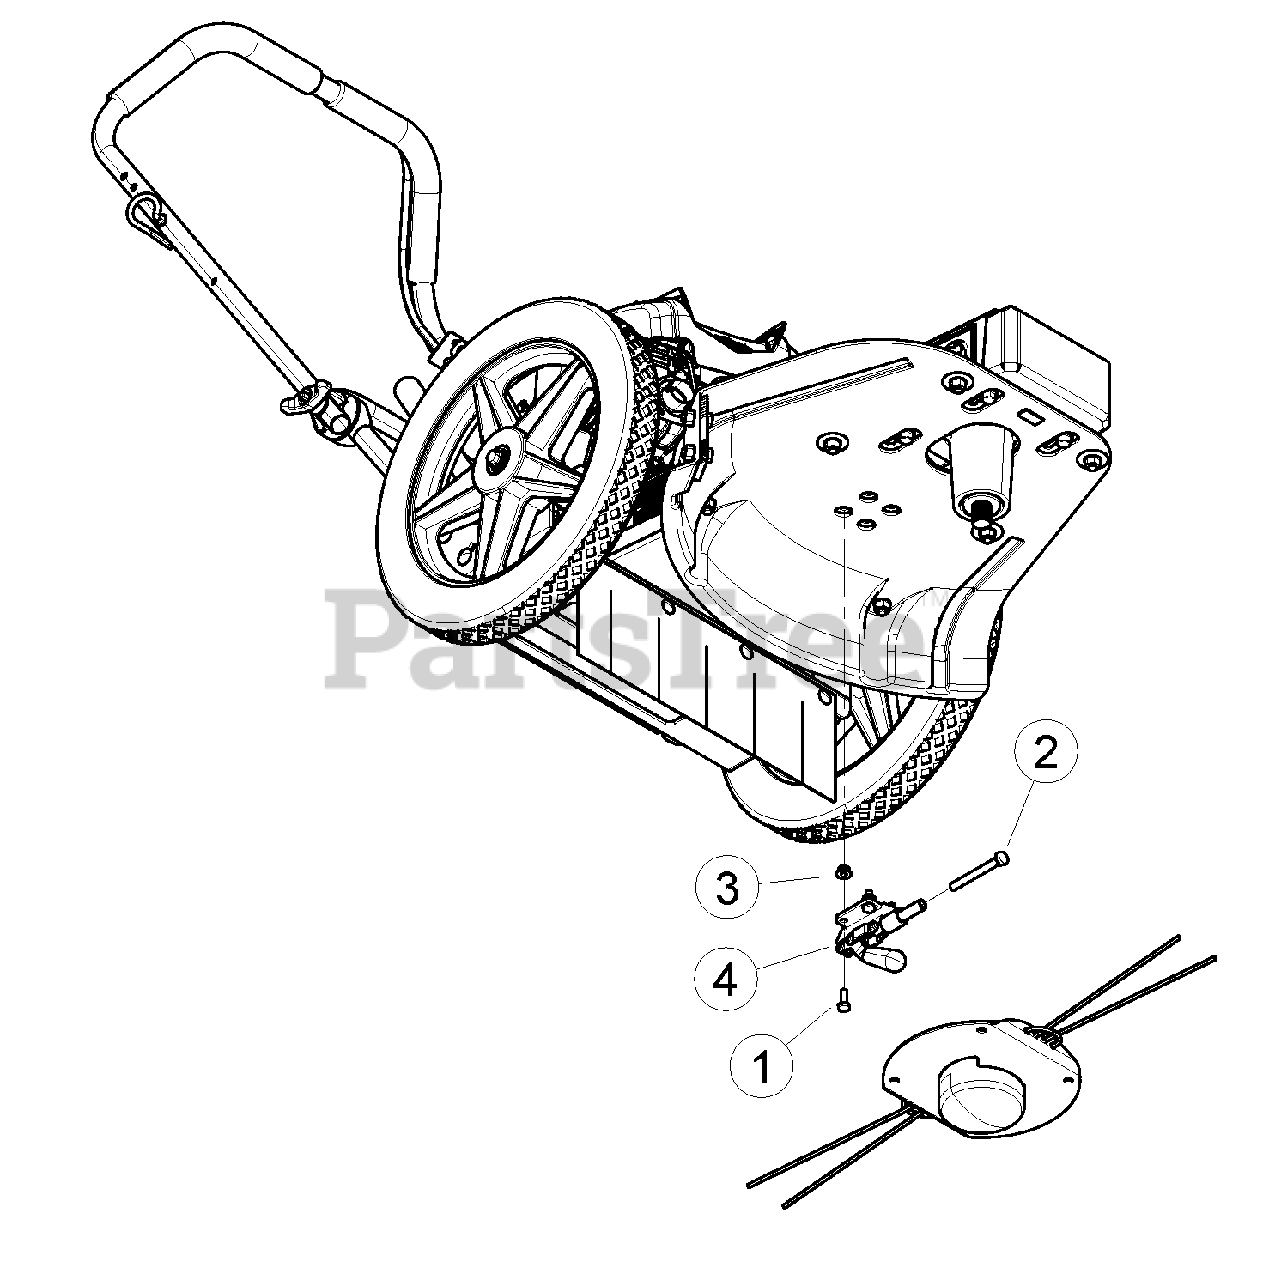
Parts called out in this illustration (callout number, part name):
1	BOLT, 1/4 X 3/4 HEX HD
2	BOLT, 5/16 NCX 2-3/4 GR5 HCPS ZP
3	NUT, 1/4-20 NYLOCK FLANGE
4	CLAMP, STRAIGHTLINE 600 LB
